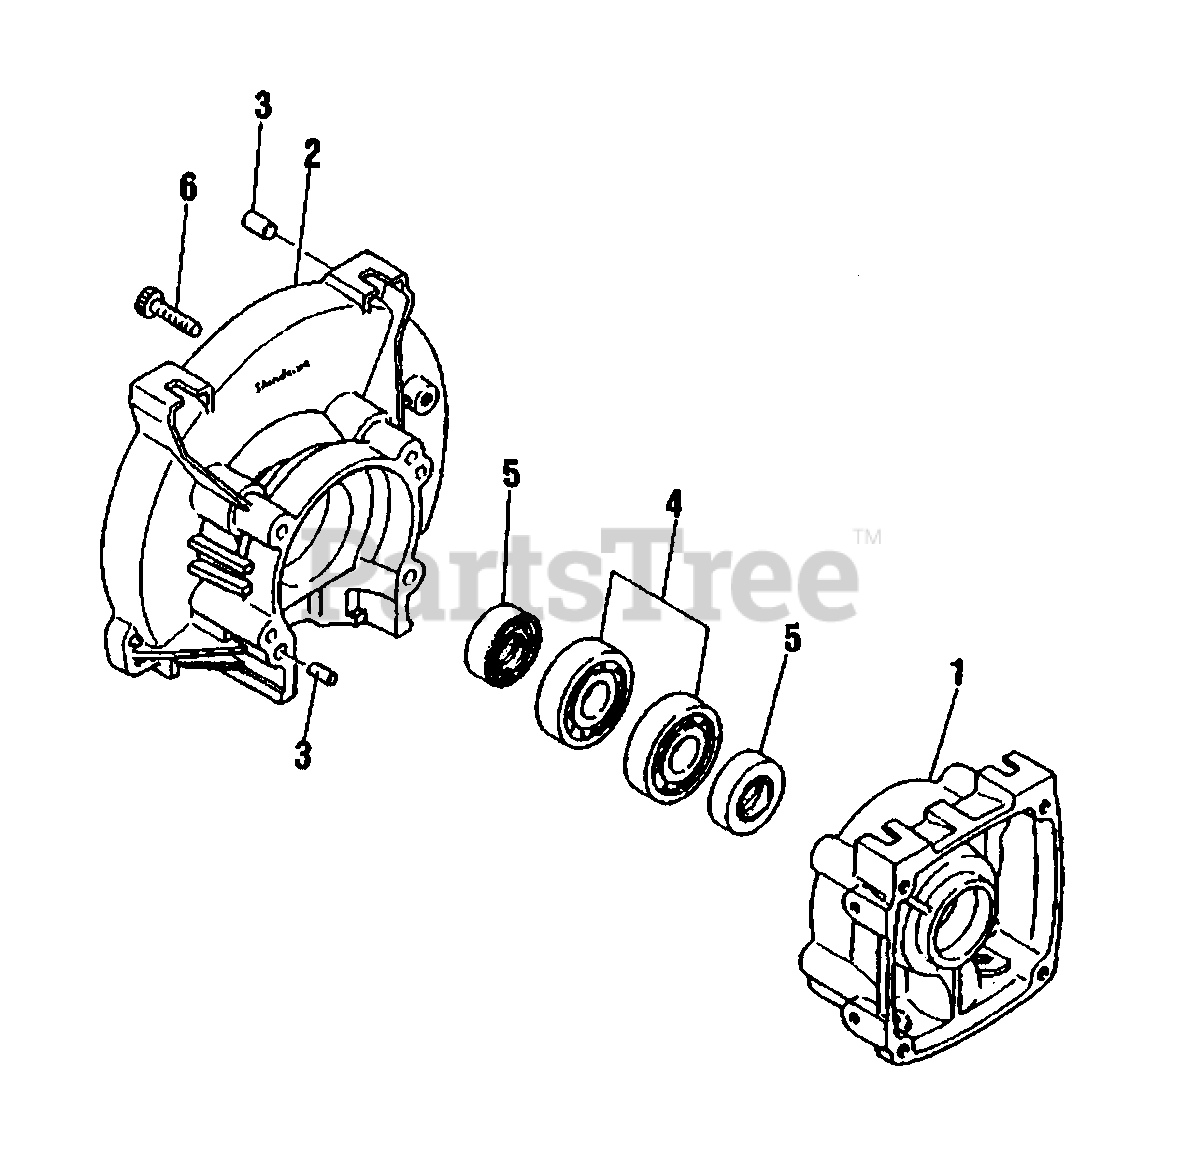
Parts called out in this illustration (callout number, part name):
1	CRANKCASE S
2	CRANKCASE M
3	PIN, LOCATING
4	BEARING, BALL
5	SEAL, OIL 16
6	BOLT 5×30
